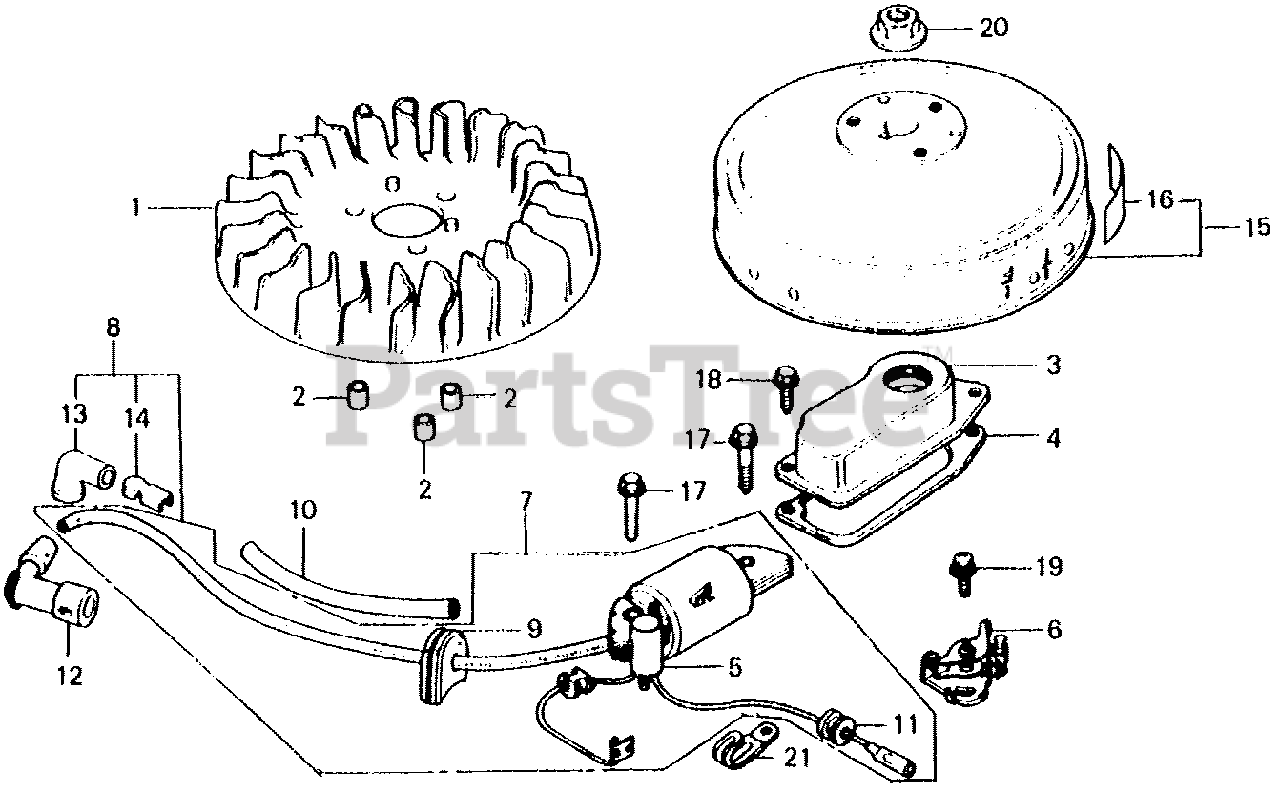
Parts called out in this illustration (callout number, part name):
1	FAN, COOLING
2	COLLAR, FAN
3	COVER, POINTS
4	GASKET, POINT COVER (NOT AVAILABLE)
4	GASKET, POINT COVER
5	CONDENSER
6	POINTS ASSY.
8	COIL, IGNITION
9	GROMMET, WIRE
11	GROMMET, PRIMARY WIRE
13	CAP, IGNITION (SUMITOMO)
13	CAP, IGNITION (TOYO)
14	TERMINAL, PLUG
15	FLYWHEEL
15	FLYWHEEL (POINT)
16	MARK, FLYWHEEL CAUTION
17	BOLT, FLANGE (6X32)
18	BOLT, FLANGE (5X10)
19	SCREW-WASHER (5X12)
20	NUT, SPECIAL (14MM)
21	CLIP, CABLE
